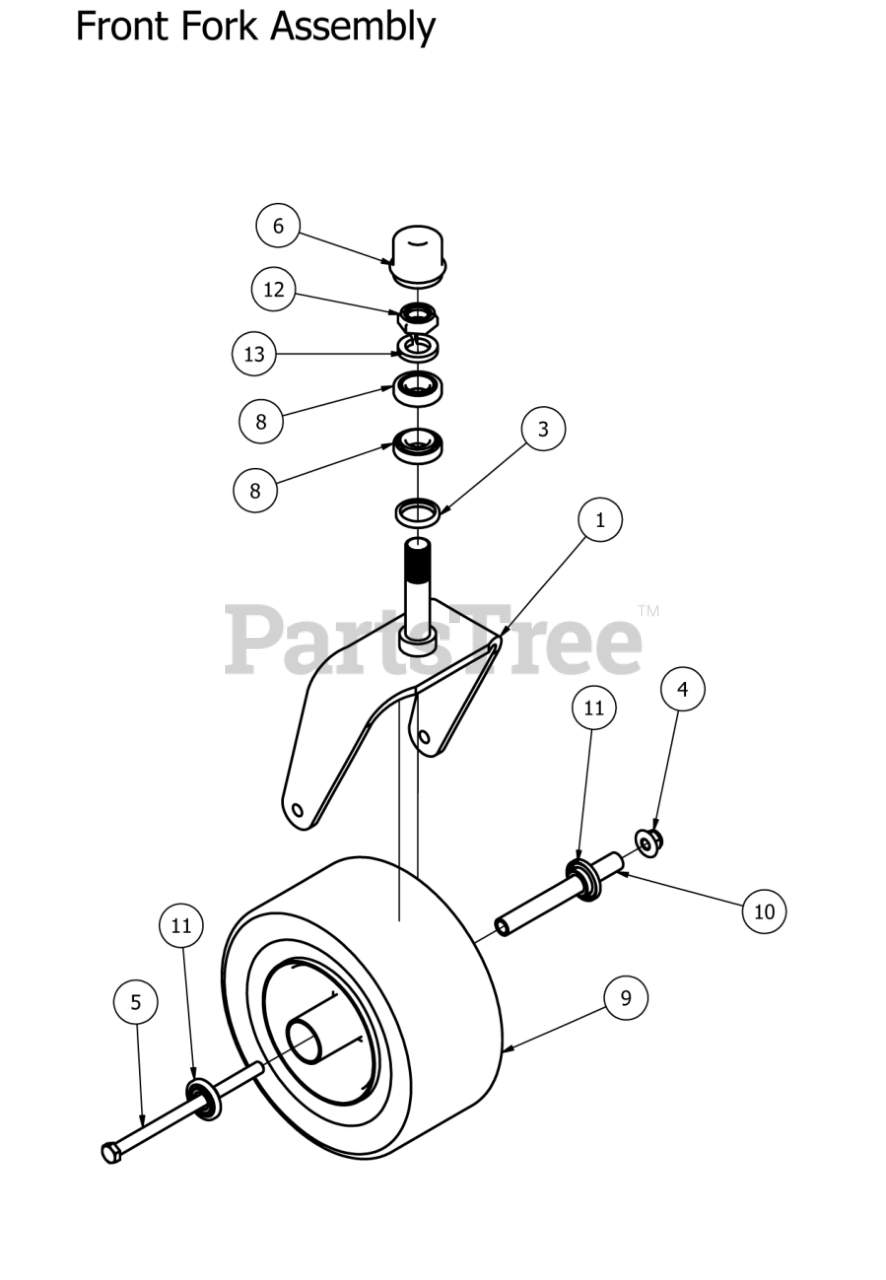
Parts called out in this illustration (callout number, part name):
1	Front Fork
4	1/2-13 Nylon Flange Nut-Orange
5	1/2" x 9" Bolt
6	Dust Cover
9	Tire and wheel assembly
10	Front Wheel Spanner
11	Wheel Bearing
12	1" Fine Thread Nut
13	1" Lock Washer
